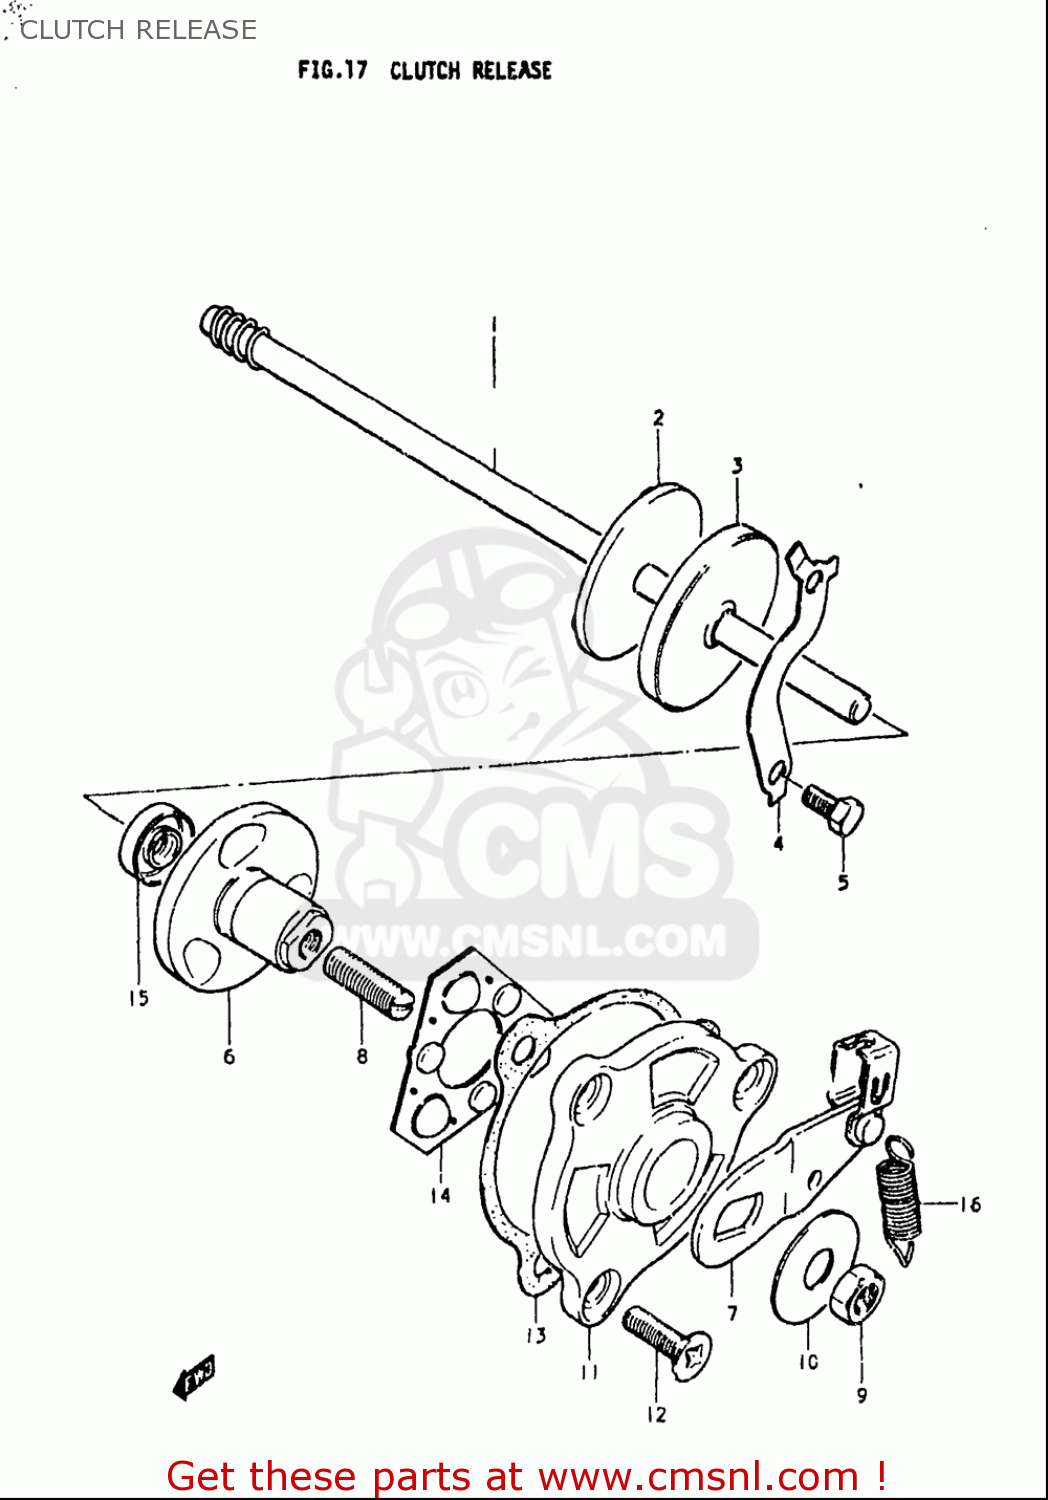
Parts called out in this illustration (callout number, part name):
1	ROD ASSY,CLUTCH RELEASE
2	HOLDER,CLUTCH PUSH ROD
3	SEAL,OIL(8X47X8)
4	RETAINER,CL PUSH ROD OIL SEAL
5	BOLT
6	GUIDE,CLUTCH RELEASE,OUTER
8	SCREW
9	NUT
10	WASHER(8.5X26X1.2)
12	SCREW
13	GASKET,BALL GUIDE (NAS)
14	BALL,CLUTCH RELEASE
15	SEAL,OIL(8X20X7)
16	SPRING
